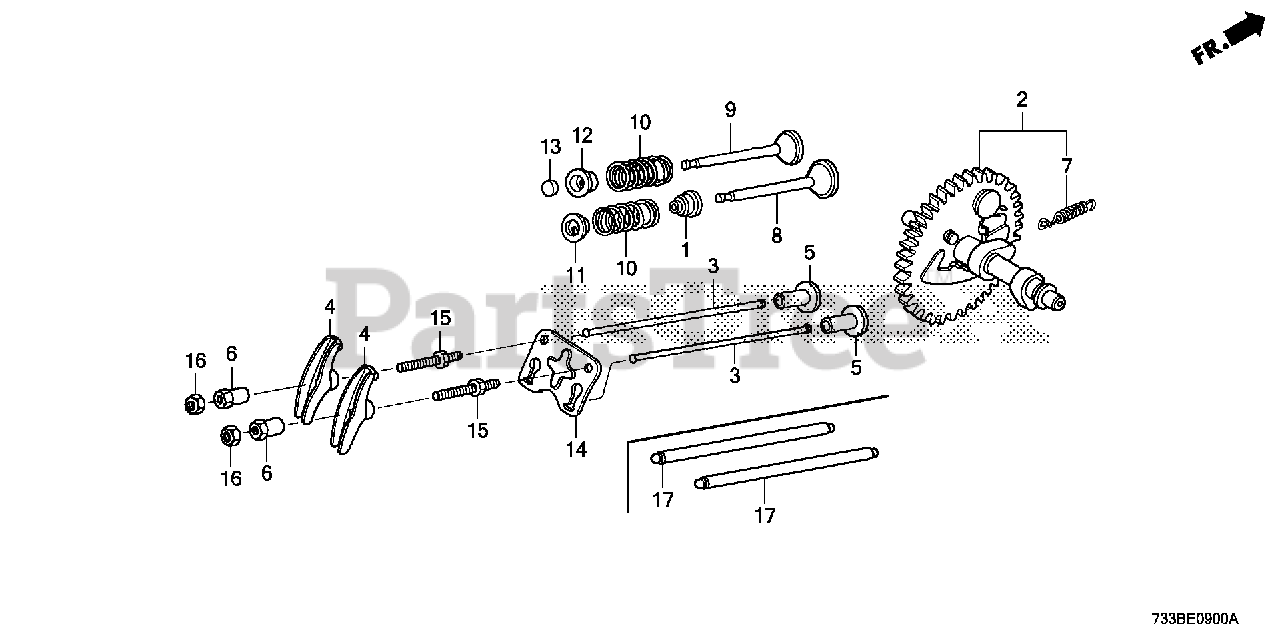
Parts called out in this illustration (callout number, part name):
1	SEAL, VALVE STEM
2	CAMSHAFT ASSY.
3	ROD, PUSH
4	ARM, VALVE ROCKER
5	LIFTER, VALVE
6	PIVOT, ROCKER ARM
7	SPRING, WEIGHT RETURN
8	VALVE, IN.
9	VALVE, EX.
10	SPRING, VALVE
11	RETAINER, IN. VALVE SPRING
11	RETAINER, VALVE SPRING (EXHAUST SIDE)
12	RETAINER, EX. VALVE SPRING
13	ROTATOR, VALVE
14	PLATE, PUSH ROD GUIDE
15	BOLT, PIVOT (8MM)
16	NUT, PIVOT ADJ.
